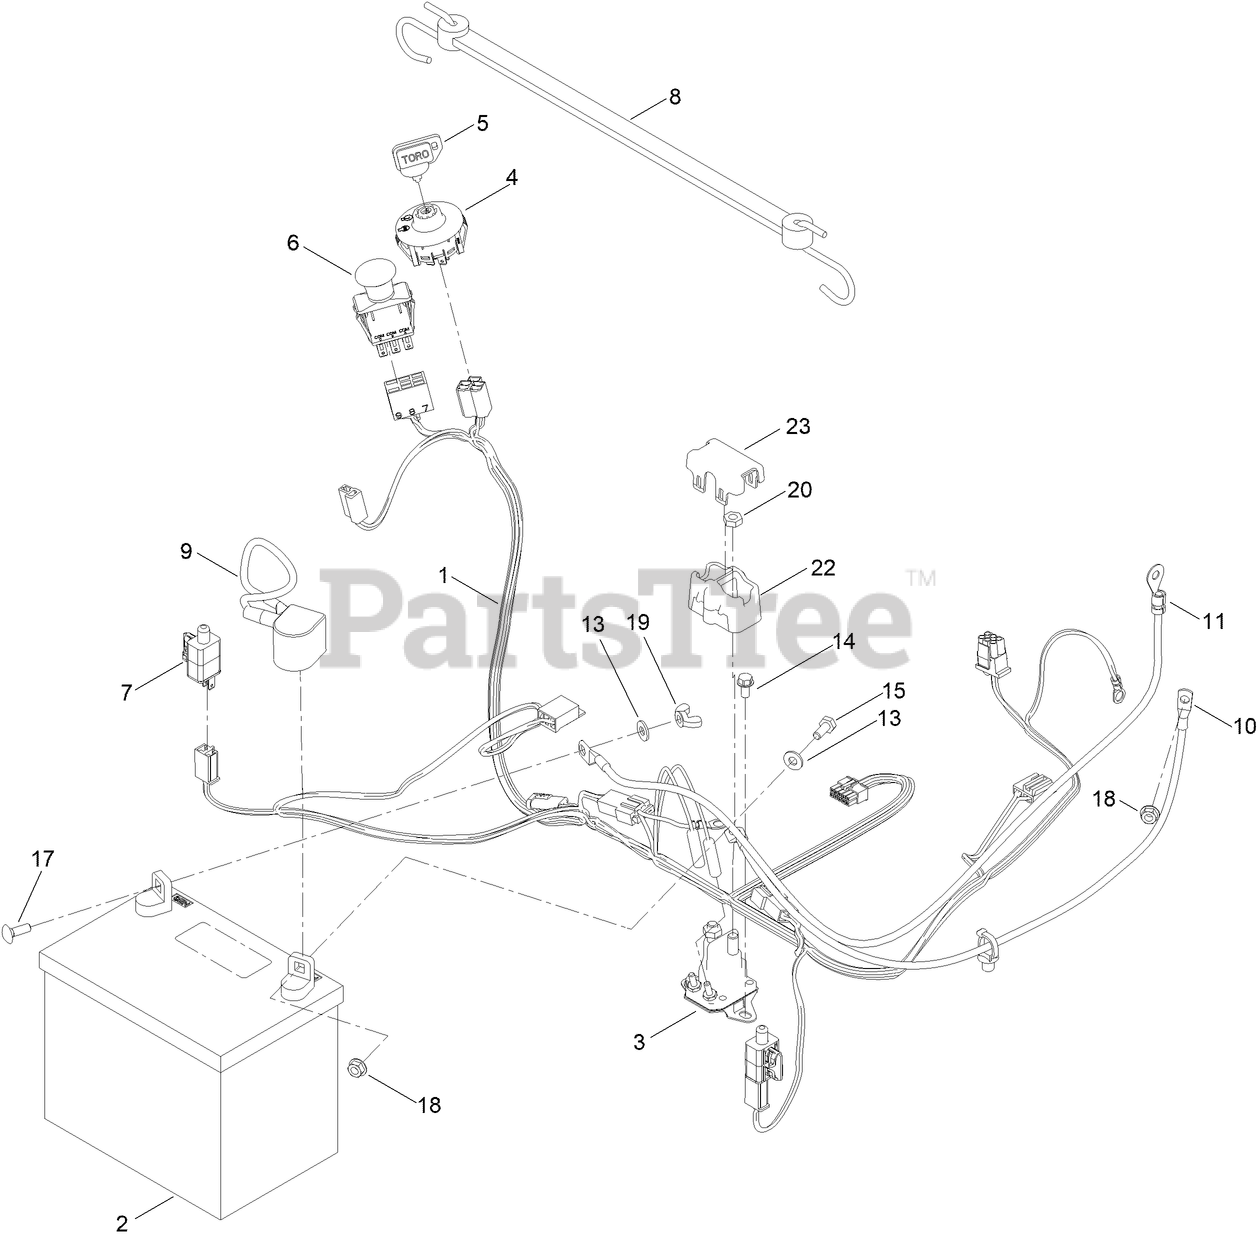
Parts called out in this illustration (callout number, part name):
1	HARNESS-WIRE
2	BATTERY
3	SOLENOID
4	SWITCH-IGNITION
5	KEY-IGNITION
6	SWITCH-PTO
7	SWITCH
8	STRAP-RUBBER
9	CABLE-BATTERY, POS
10	CABLE-BATTERY, RED (8 GAUGE)
11	CABLE-BATTERY, BLACK
13	WASHER-FLAT
14	SCREW-HWH
15	SCREW-HH
17	BOLT-CARR
18	NUT-HF
19	NUT-WING
20	NUT-HJ
22	COVER-SOLENOID
23	CAP-SOLENOID
